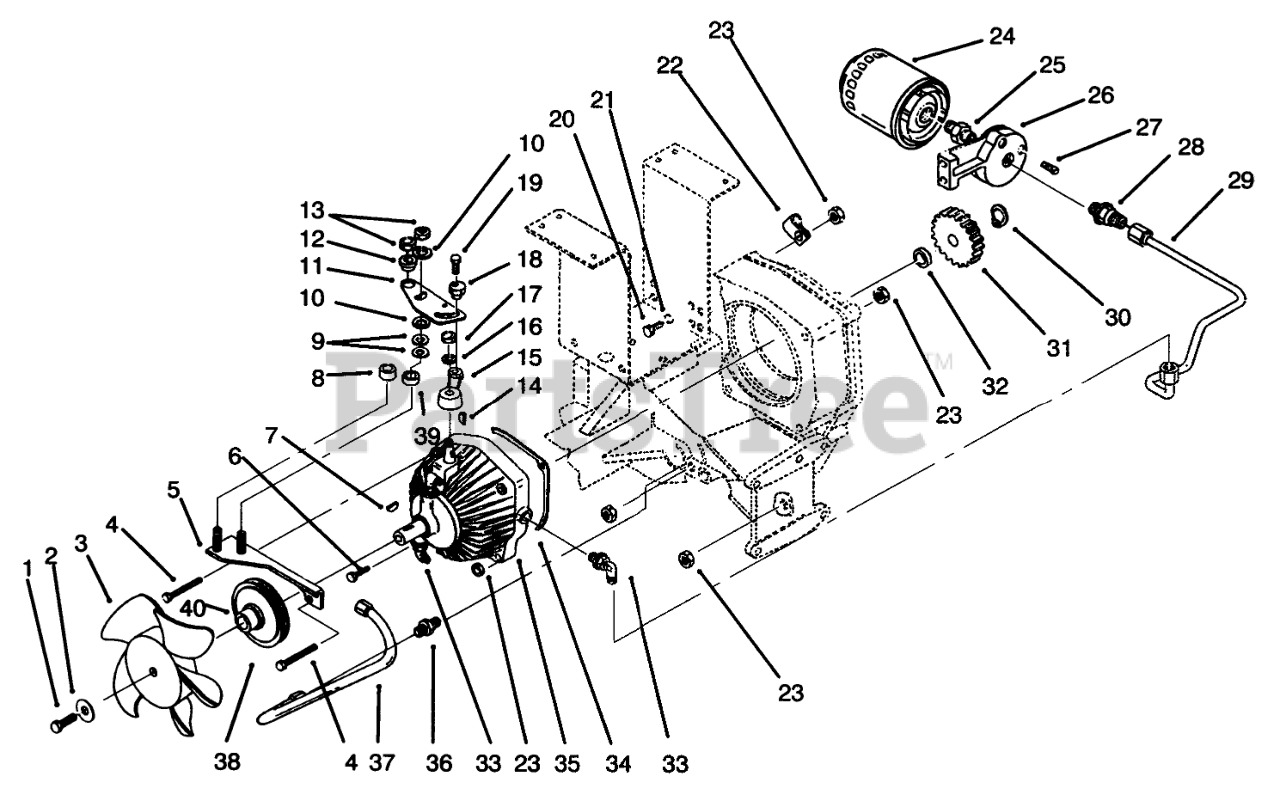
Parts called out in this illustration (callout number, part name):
2	WASHER
3	NYLON FAN-L-CW
4	SCREW-HH
5	ASSY-PLATE B
7	KEY-WOODRUFF
8	SPACER-PIVOT
9	WASHER-SPRING DISC
10	FRICTION WASHER
11	CAM-SPEED CONTROL (NS)
12	CAM-SPACER
14	KEY-WOODRUFF
15	ARM-SPEED CONTROLB
16	WASHER-FLAT
17	NUT-LOCK, NI
19	Screw-HH
20	SCREW-HH
21	WASHER-LOCK
22	CLIP
23	NUT-LOCK, NI
24	OIL FILTER ASM
25	FITTING
26	BASE-FILTER
28	Fitting-Hyd., Straight (Incl. "O" Ring)
29	ASS'Y-TUBE FILTER
30	RING-SNAP, EXTERNAL
31	GEAR 20 TEETH DRIVE
32	SPACER GEAR
33	ELBOW
34	GASKET
35	Pump & Motor
36	FITTING-TUBE
37	ASSY-TUBE SUCTION
38	PULLEY
39	SPACER-FRICTION
